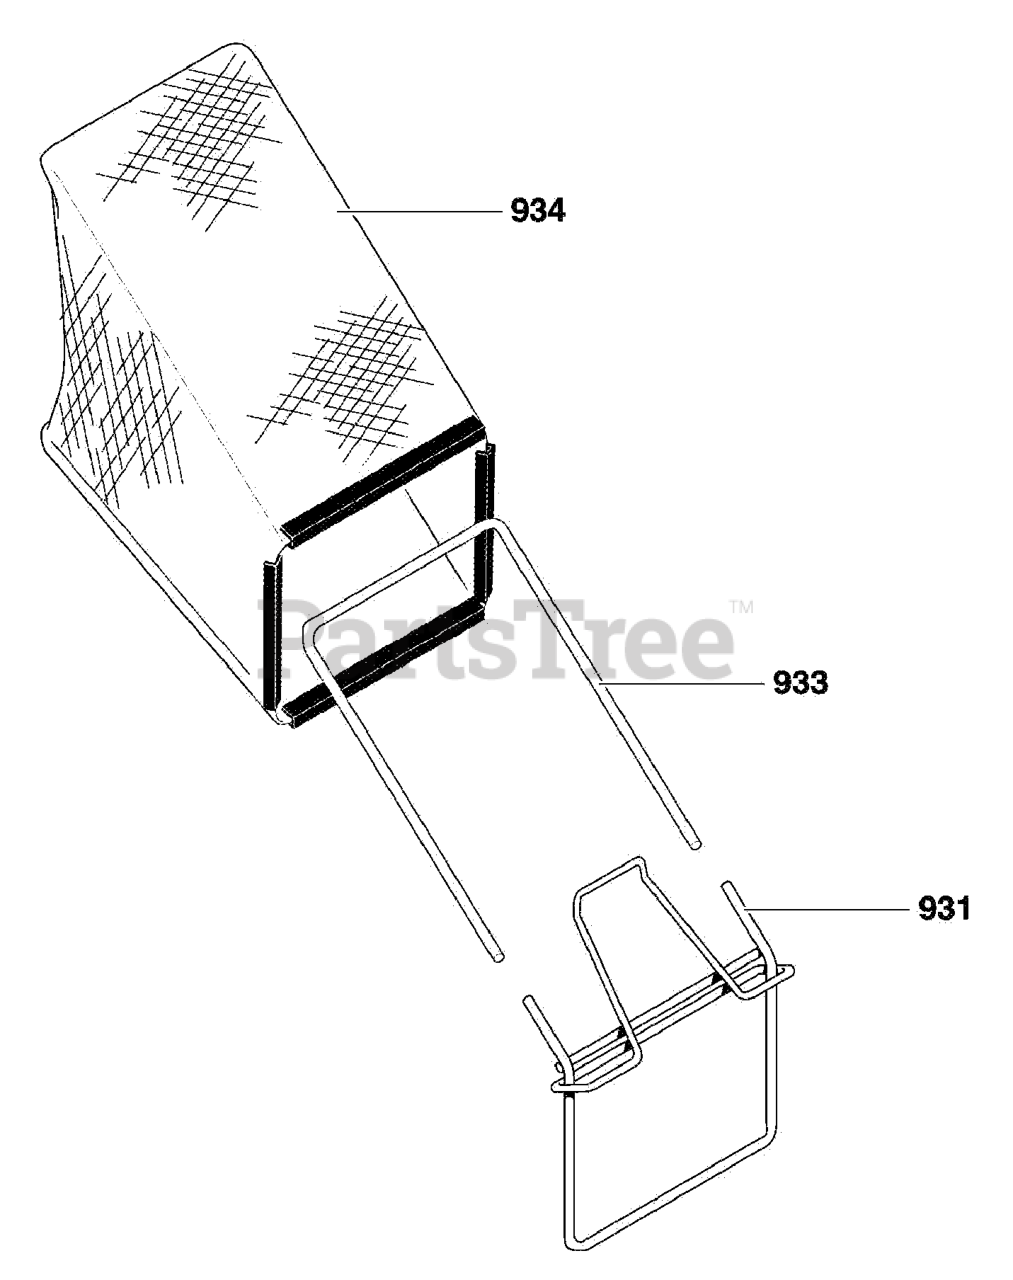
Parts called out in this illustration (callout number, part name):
931	ASSY, BAG FRAME
933	FRAME, BAG TOP
934	BAG, 21
